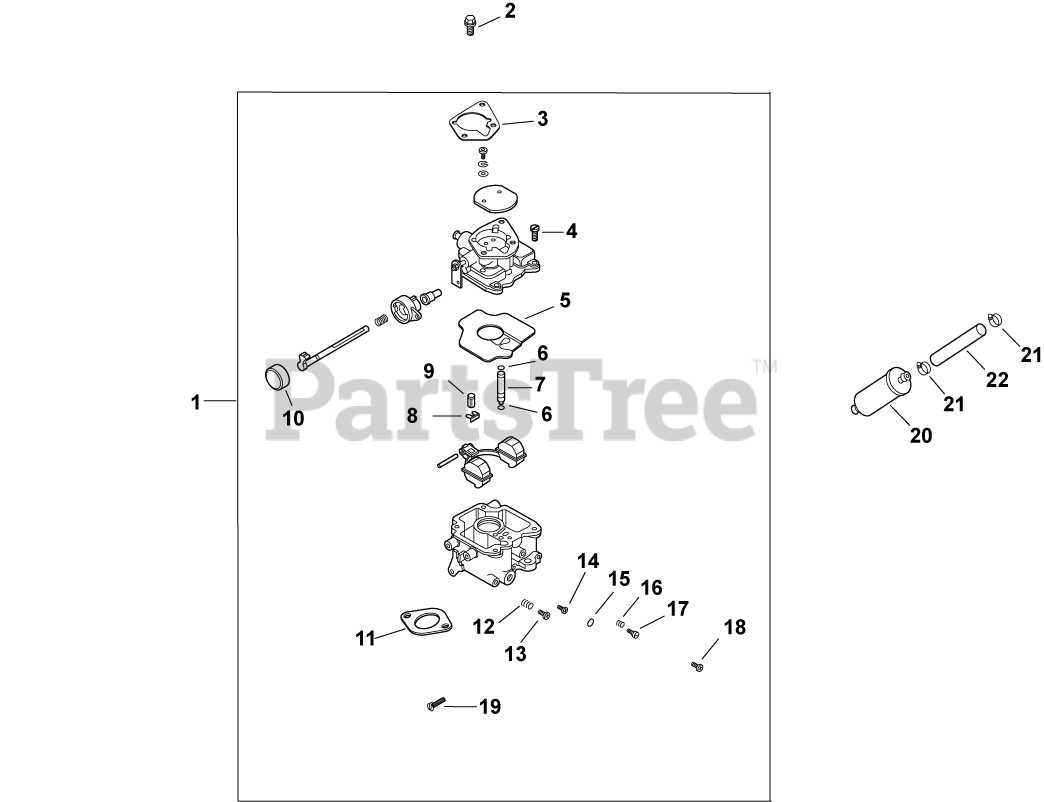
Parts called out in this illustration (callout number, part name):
1	KIT, CARBURETOR W/GASKETS
2	SCREW, FLG M6X1.0X30
3	GASKET, AIR CLEANER BASE
4	SCREW, CARBURETOR BODY
5	GASKET, CARBURETOR BODY
6	O-RING, SLOW JET
7	JET, SLOW
8	CLIP, INLET NEEDLE VALVE
9	VALVE, INLET NEEDLE
10	CAP, CHOKE LEVER
11	GASKET, CARBURETOR
12	SPRING, IDLE SPEED ADJ SCREW
13	SCREW, IDLE
14	JET, MAIN
15	O-RING, MAIN JET SCREW
16	SPRING, IDLE NEEDLE
17	NEEDLE, IDLE
18	SCREW, FLG M8X1.00X10
19	SCREW, THROTTLE STOP
20	FILTER, FUEL (9-12 MICRON)-USE 24 050 13
21	CLAMP, HOSE (KM)-USE 25 237 31-S
22	HOSE,LW PERM.FUEL 24.00"-USE 25 111 81-S
